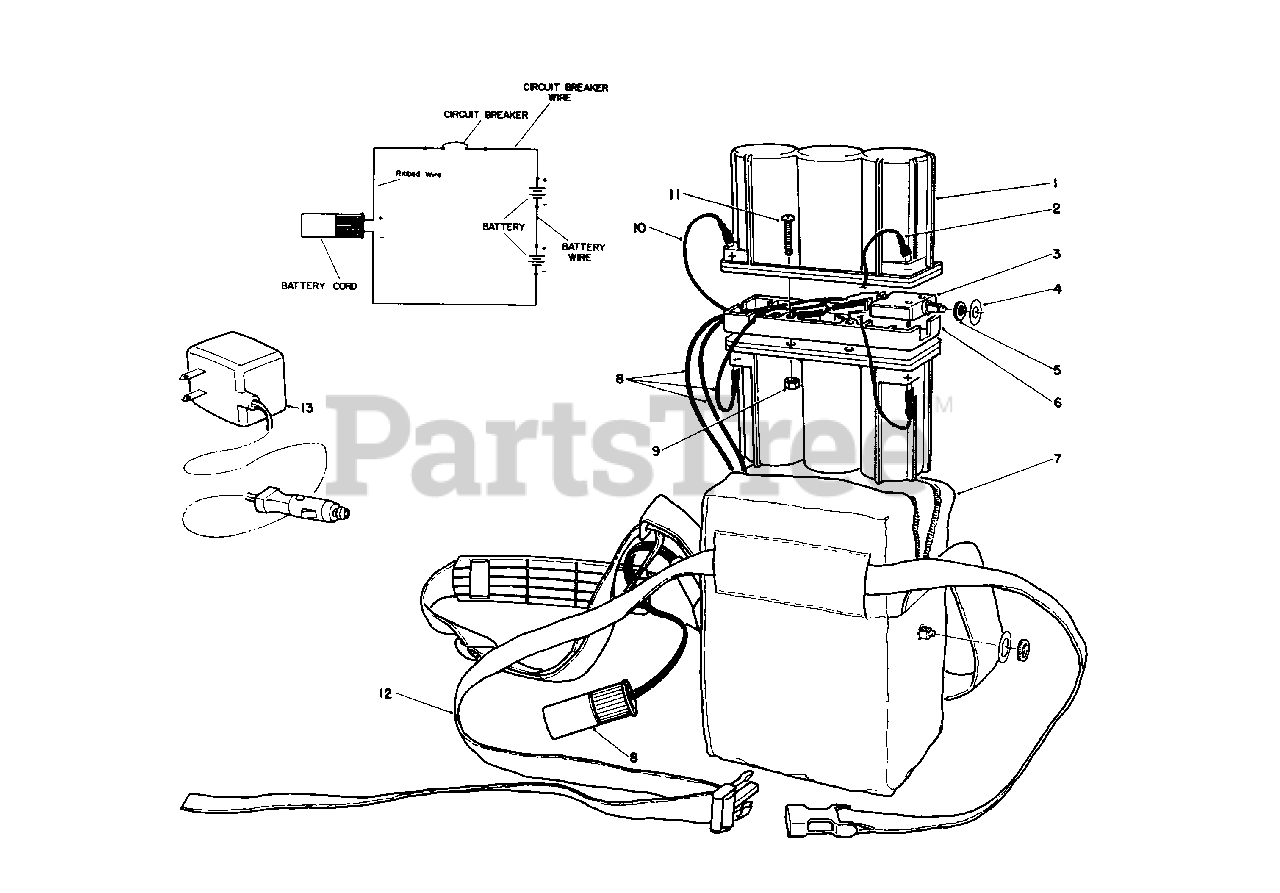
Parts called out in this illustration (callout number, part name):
1	Battery-6 Volt
2	Wire-Battery
3	Circuit Breaker
4	Plate-Breaker, Circuit
5	Nut-Knurled
6	Spacer-Battery
7	Pack-Soft
8	Cord-Battery
10	Wire-Breaker, Circuit
11	Screw-Phillips, Pan Hd.
13	Charger-12 Volt
